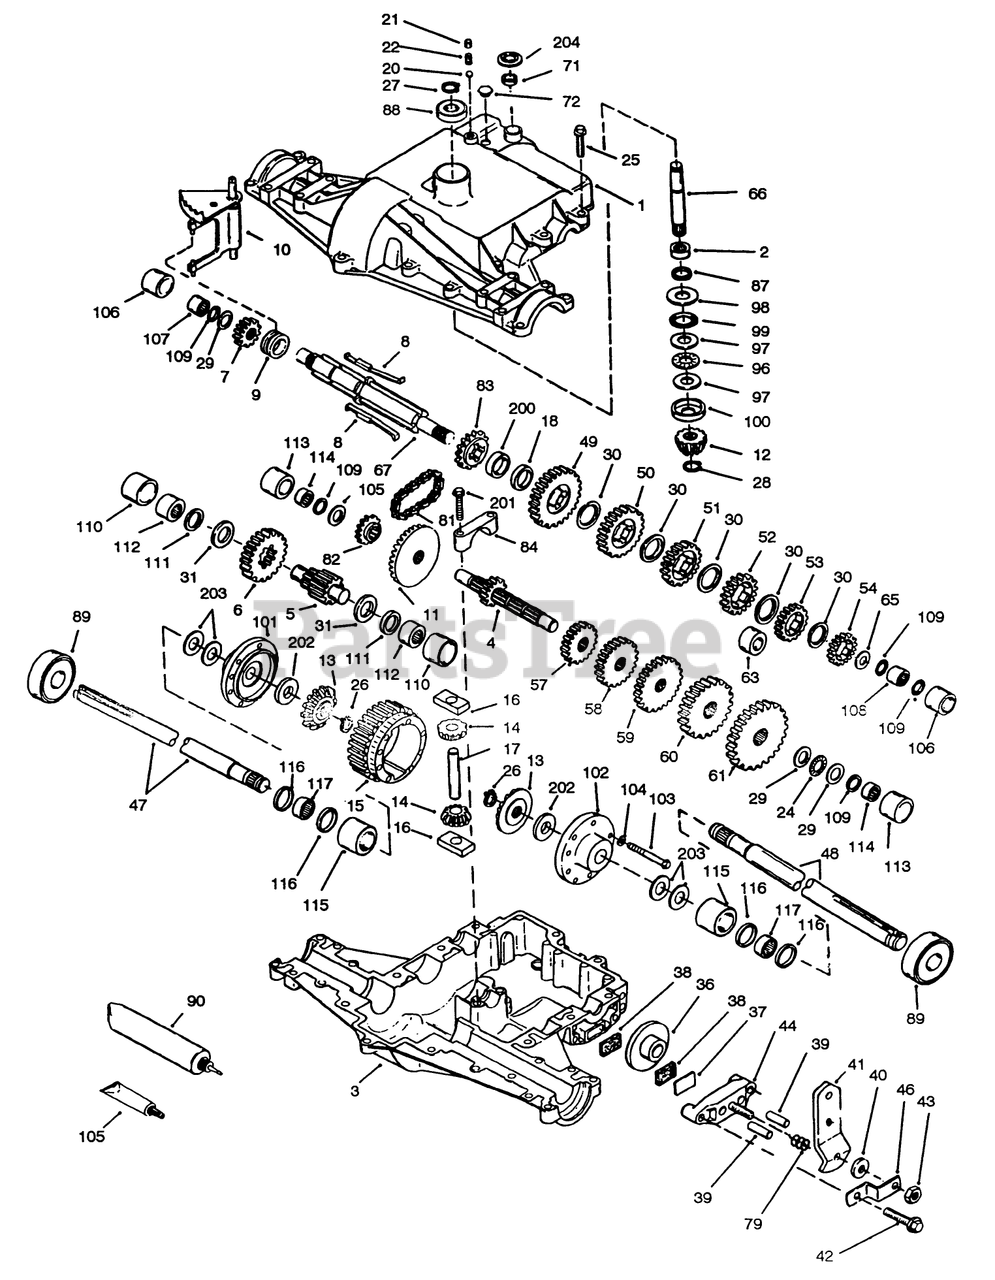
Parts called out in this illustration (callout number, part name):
1	Cover-Transaxle (Only On: 72042, 72062)
2	Bearing-Needle (Only On: 72042, 72062)
3	Case-Transaxle (Only On: 72042,72062)
4	Countershaft-Gear 9t (Only On: 72042, 72062)
5	Shaft-Output (Only On: 72042, 72062)
6	Gear-Output 35t (Only On: 72042,72062)
7	Gear-Spur 15t (Only On: 72042,72062)
8	Key-Shift (Only On: 72042, 72062)
9	Collar-Shift
10	Fork-Shift (Only On: 72042,72062)
11	Gear-Bevel 33t (Only On: 72042, 72062)
12	Pinion-Input Bevel 13t (Only On: 72042, 72062)
13	Gear-Bevel
14	Pinion-Bevel
15	Gear-Ring (Only On: 72042,72062)
16	Biock-Drive
17	Pin-Drive
18	Spacer .350-.340 Thick (Only On: 72042, 72062)
20	Ball-Steel
21	Screw-Set
22	Spring
24	Bearing-Thrust
25	Screw 5/16-18x1 1/4 (Only On: 72042, 72062)
26	Ring-Snap
27	Ring-Snap
28	Ring-Retainer
29	Washer
30	Washer
31	Washer (Only On: 72042,72062)
36	Washer (Only On: 72042, 72062)
37	Brake Pad Plate
38	Pad-Brake 2/Pkg
39	Dowel Pin
40	Washer
41	Lever-Brake
42	Ring Set (.020 O S)
43	Locknut
44	Nozzle-Carburetor
46	Bracket
47	Axle 12 9/16" Long (Only On: 72042,72062)
48	Axle 16 7/16" Long (Only On: 72042, 72062)
49	Gear-Spur 41t (Only On: 72042,72062)
50	Gear-Spur 35t (Only On: 72042,72062)
51	Gear-Spur 30t (Only On: 72042, 72062)
52	Gear Spur 25t (Only On: 72042,72062)
53	Gear Spur 22t (Only On: 72042,72062)
54	Gear Spur 19t
57	Gear Spur 15t (Only On: 72042, 72062)
58	Gear Spur 20t (Only On: 72042, 72062)
59	Gear Spur 25t (Only On: 72042, 72062)
60	Gear Spur 28t (Only On: 72042,72062)
61	Gear Spur 30t (Only On: 72042,72062)
65	Washer
66	Shaft-Input 30.910" Lg (Only On: 72042, 72062)
67	Shaft-Shifter/Brake (Only On: 72042, 72062)
71	Cut Seal-Square
79	Piston ASM (.020 O S)
81	Chain-Roller
82	Sprocket 10t
83	Sprocket (14 teeth)
84	Cap-Bearing (Only On: 72042, 72062)
87	Seal Oil
88	Bearing-Ball
89	Bearing-Ball
90	Grease 32 Oz
96	Bearing-Thrust (Only On: 72042,72062)
97	Washer
98	Washer (Only On: 72042, 72062)
99	O Ring (Only On: 72042,72062)
100	Washer-Cupped (Only On: 72042,72062)
101	Carrier-Differential (Only On: 72042, 72062)
102	Carrier-Differential (Only On: 72042, 72062)
103	Screw-Hex Hd.
104	Lockwasher
105	Washer (Only On: 72042,72062)
106	Sleeve (Only On: 72042,72062)
107	Bearing-Needle (Only On: 72042,72062)
108	Bearing-Needle (Only On: 72042, 72062)
109	O Ring
110	Sleeve (Only On: 72042, 72062)
111	Ring-Square Cut (Only On: 72042, 72062)
112	Bearing-Needle (Only On: 72042, 72062)
113	Sleeve (Only On: 72042, 72062)
114	Bearing-Needle (Only On: 72042,72062)
115	Sleeve (Only On: 72042,72062)
116	Ring-Square Cut (Only On: 72042,72062)
117	Bearing-Needle (Only On: 72042,72062)
150	Gasket Eliminator
200	Spacer .276-.268 Thick (Only On: 72042, 72062)
201	Ring Set (.020 O S)
202	Washer
203	Washer
204	Pushnut
